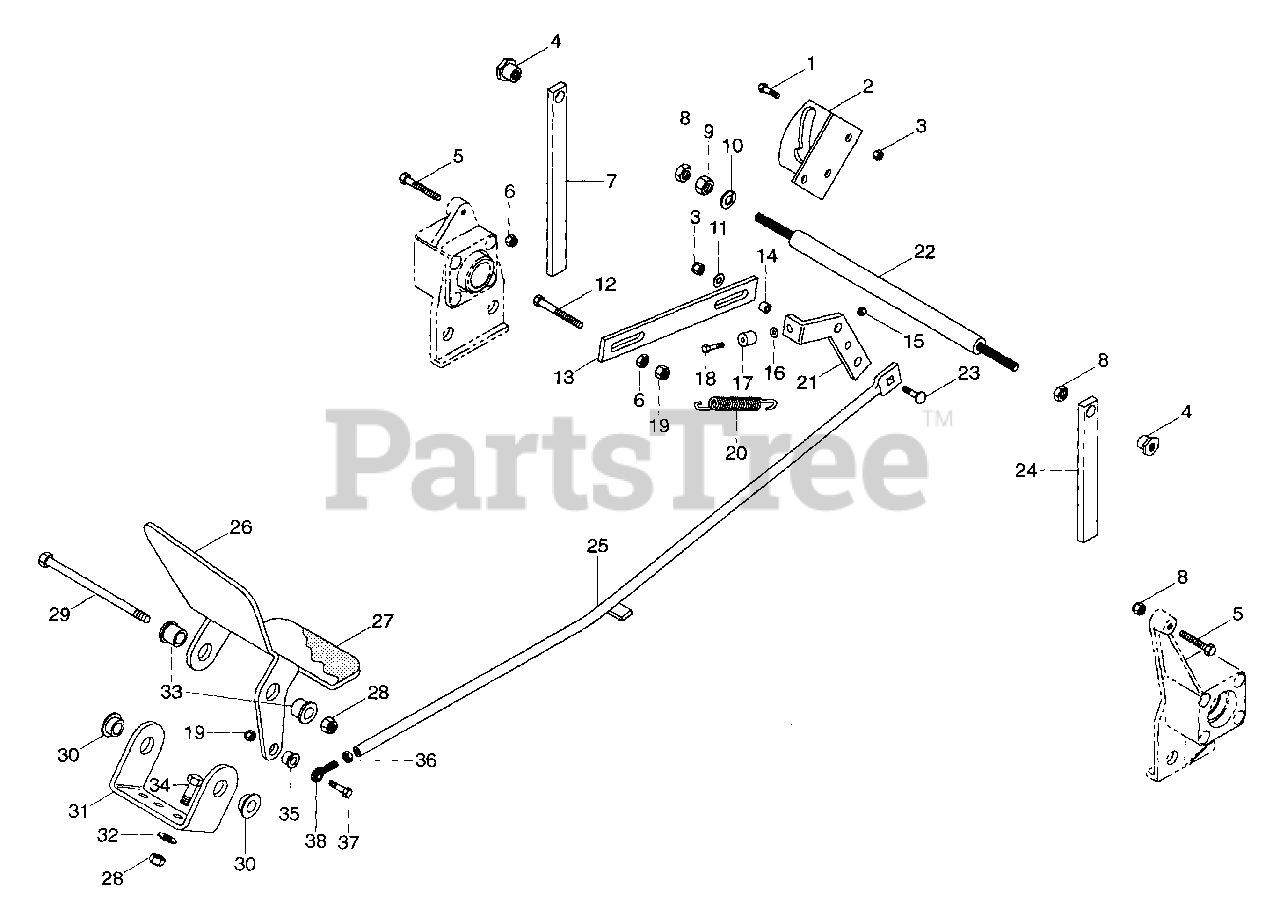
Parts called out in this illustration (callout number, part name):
1	Bolt-Hex .31-18 x 1.00 Grade 5
2	Weldment, Forward-Reverse Actuating
3	Nut-Locking-Nylon .312-18 Grade 2
4	Bushing-Flange .500 x .875 x .700
5	Bolt-Hex .38-16 x 2.50
6	Nut-Hex .375-16 Grade 2
7	Spring, Reverse Clutch
8	Nut-Jam .50-13 Grade 2
9	Nut .50-13
10	Washer-Lock .500 x .151
11	Washer-Flat-Steel .313 x .875 x .065
12	Bolt-Hex .38-16 x 3.00
13	Strap, Neutral Detent
14	Bushing-Steel .328 x .500 x .500
15	Nut-Locking-Nylon .250-28 Grade 2
16	Washer-Flat-Steel .281 x .620 x .065
17	Roller, Clutch Cam .250 x .750 x .5625
18	Bolt-Hex .25-28 x 1.38
19	Nut-Locking-Nylon .375-16 Grade 2
20	Spring-Tens .062 x .50 x 3.1
21	Arm, Forward-Reverse Clutch Roll
22	Rod, Forward-Reverse Slide
23	Bolt-Round Head Square Neck .31-18 x 1.25
24	Spring, Forward-Reverse Clutch
25	Weldment, Forward-Reverse Rod
26	Pedal, Foot Clutch
27	Pad, Foot Clutch Pedal
28	Nut-Locking-Nylon .50-13 Grade 5
29	Bolt-Hex .50-13 x 6.50
30	Bushing-Flange .767 x 1.0 x .580 x 1.48
31	Bracket, Clutch Pedal Pivot
32	Washer-Flat-Steel .531 x 1.250 x .100
33	Bushing-Flange .515 x .750 x .745 x 1.00
34	Bolt-Hex .50-13 x 1.25 Grade 5
35	Bushing-Flange .320 x .620 x .312
36	Nut-Jam .375-24
37	Bolt-Hex .38-16 x 1.25 Grade 5
38	Rod End, Male
